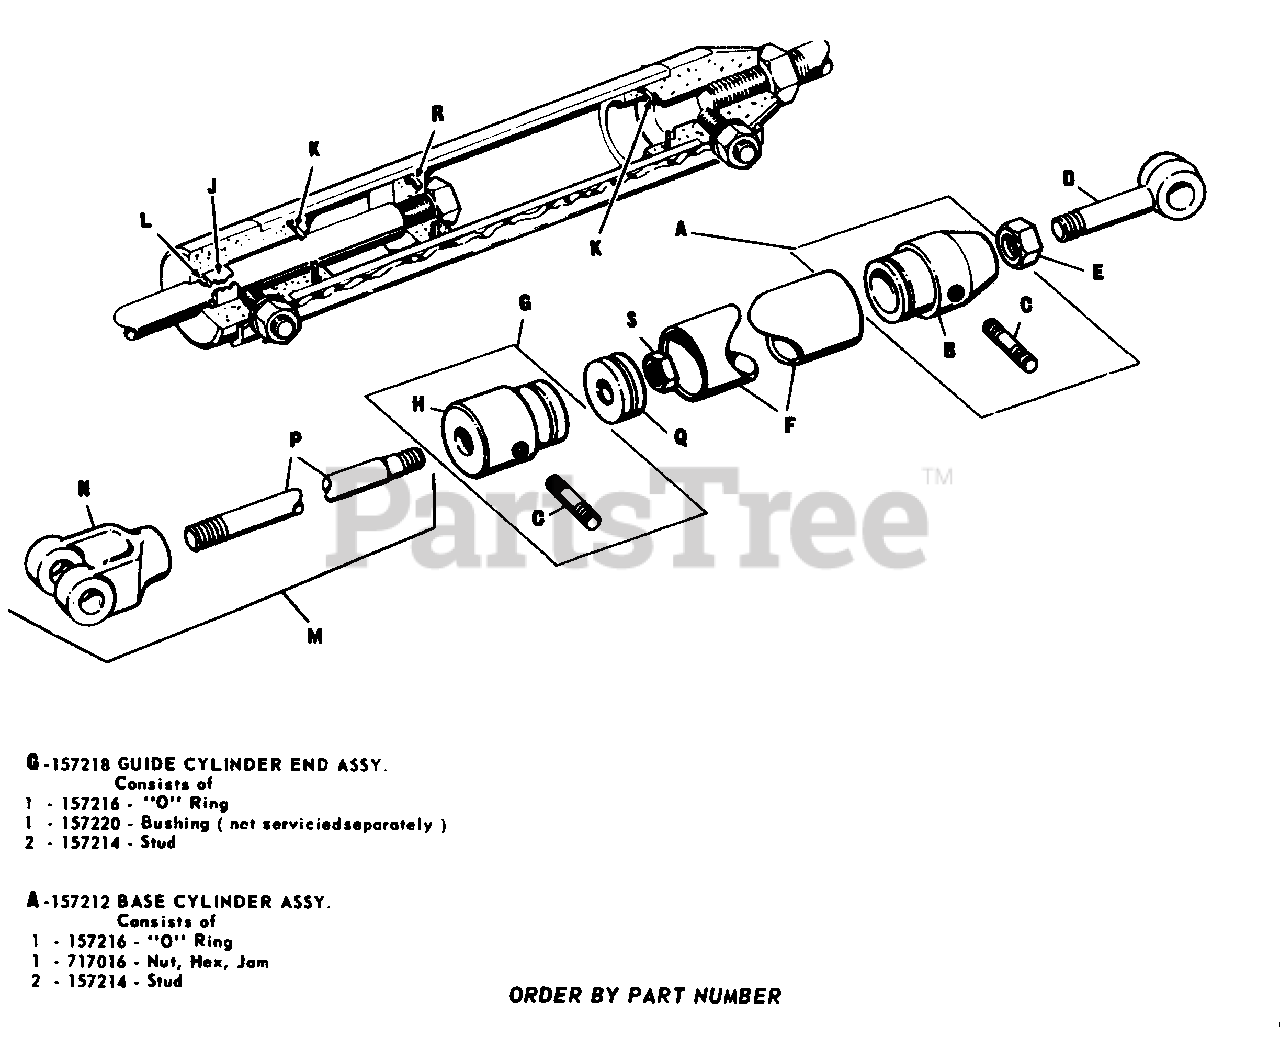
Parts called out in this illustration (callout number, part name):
A	Cylinder Base Sub-Assembly
B	Cylinder Base
C	Stud Bolt, 5/16"-18 x 7/8"
E	Jam Hex. Nut, 1/2"-20
G	Sub Assembly Guide
H	Cylinder End Guide
M	Yoke & Rod
P	Piston Rod
Q	Piston Piston
S	Full Hex. Nut
